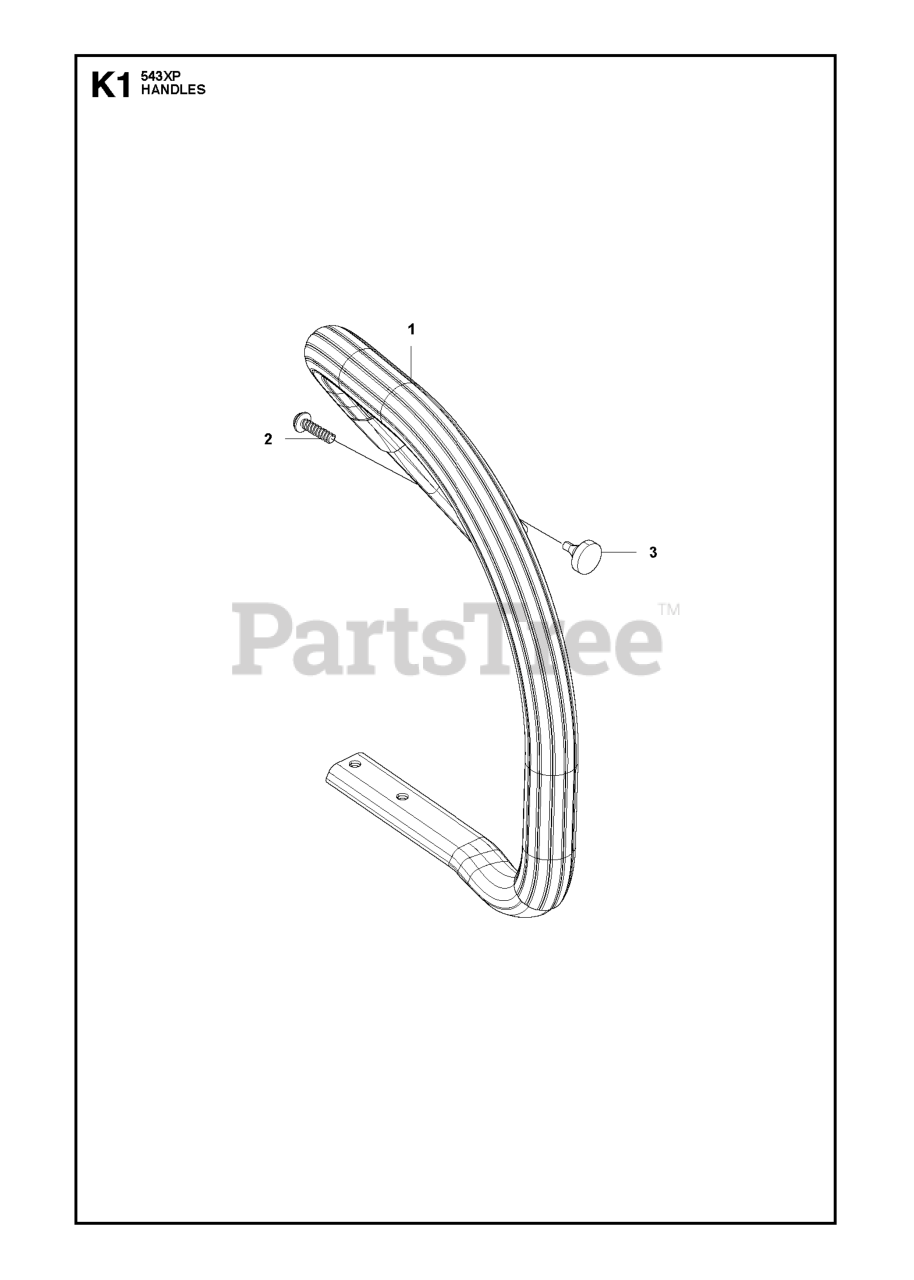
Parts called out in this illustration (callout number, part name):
1	FRONT HANDLE ASSY
2	SCREW (RPLS 267132210)
3	HELPER(P) Z285032150
